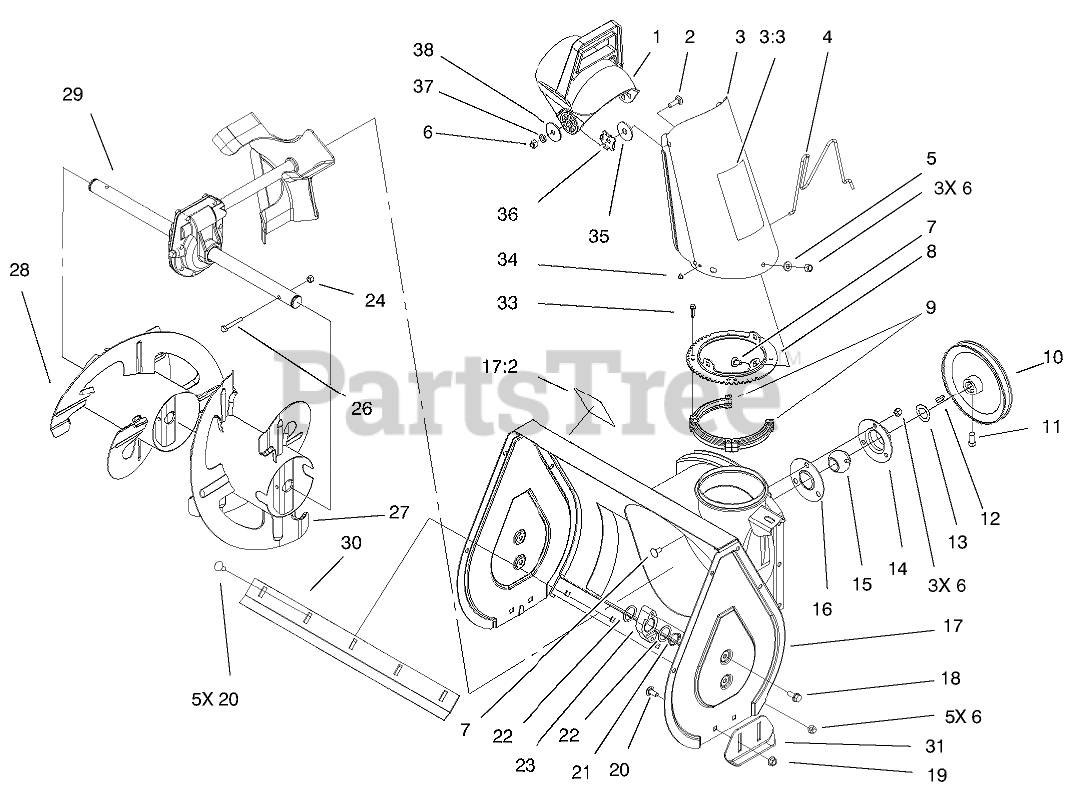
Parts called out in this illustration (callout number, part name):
1	CHUTE-DEFLECTOR
2	SCREW-CARR
3	Chute ASM (only on: 38064)
3	Chute ASM (only on: 38063)
3:3	Decal-Danger (only on: 38063)
3:3	Decal-Danger (only on: 38064)
4	WIRE-CHUTE
5	WASHER-PLAIN
6	NUT-LOCK, NI
7	SCREW-CARR
8	RING-CHUTE
9	RING-CHUTE, RETAINER
10	PULLEY
11	SCREW-SET, SQH
12	KEY-WOODRUFF
13	WASHER
14	FLANGE-CUP, BEARING
15	BEARING-BALL
16	FLANGE-CUP, BEARING
17	Auger Housing ASM Service] (only on: 38064)
17	Auger Housing ASM (only on: 38063)
17:2	Decal-Warning, Auger (only on: 38064)
17:2	Decal-Warning, Auger (only on: 38063)
18	SCREW-HWHTF
19	NUT-HF
20	BOLT-CARR
21	RING-RETAINING
22	WASHER
23	BEARING-AUGER
24	NUT-LOCK, NI
26	SCREW-HH
27	AUGER, LH
28	AUGER, RH
29	22 INCH GEAR CASE ASM
30	BLADE-SCRAPER
33	SCREW-SPECIAL
34	NUT-PUSH
35	WASHER-RUBBER
36	PLATE-FRICTION
37	WASHER-BELLEVILLE
38	WASHER-FLAT
